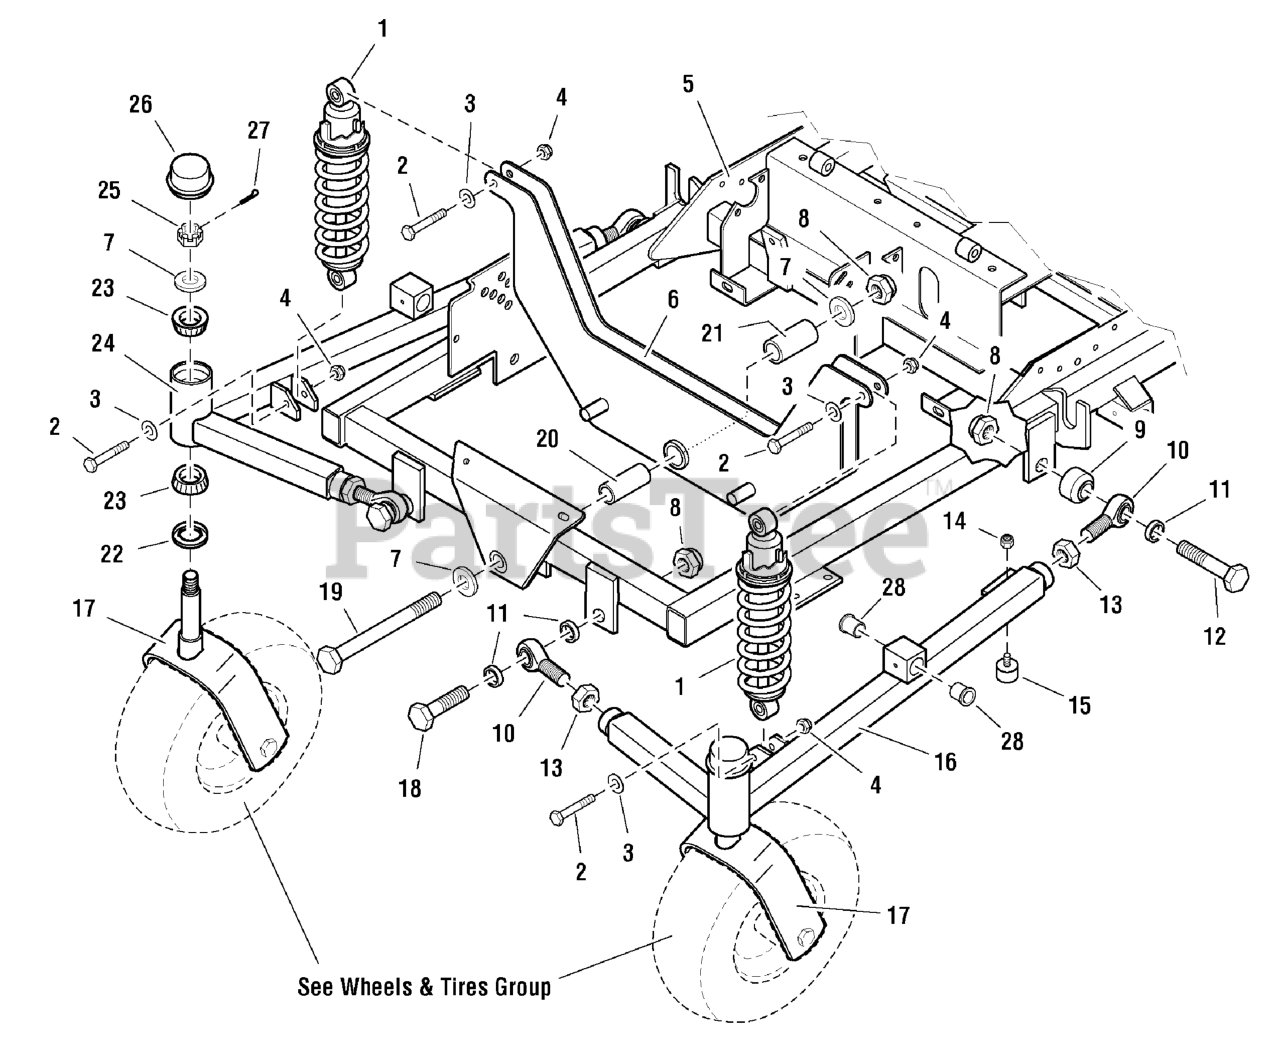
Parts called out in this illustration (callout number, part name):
1	SHOCK & SPRING ASSEMBLY
2	BOLT, 3/8-16 X 2, GD5, CZ
3	WASHER, 3/8 SAE
4	NUT, 3/8-16 HEX NYLON LOCK
5	MAIN FRAME
6	UPPER SHOCK MOUNT
7	WASHER, 3/4 SAE
8	NUT, 3/4-16 Hex Nylon Lock
9	SPACER, .75 x 1.50 x 1.00
10	BALL JOINT, 3/4-16 Male
11	SPACER, .76 x 1.00 x .25
12	BOLT, 3/4-16 x 4
13	NUT, 3/4-16 Hex Jam
14	NUT, 1/4-20 HEX NYLON LOCK
15	RUBBER BUMPER
16	SUSPENSION ARM ASSEMBLY - LH, Complete
17	CASTER YOKE
18	BOLT, 3/4-16 x 3
19	BOLT, 3/4-16 x 6
20	SPACER, .75 x 1.00 x 2.38
21	PIVOT BEARING
22	SEAL, GREASE
23	BEARING, Tapered Roller
24	SUSPENSION ARM ASSEMBLY - RH, Complete
25	NUT, 3/4-16 Hex Slotted
26	CAP
27	PIN, COTTER, 1/8 X 1-1/4
28	BUSHING, Flange
